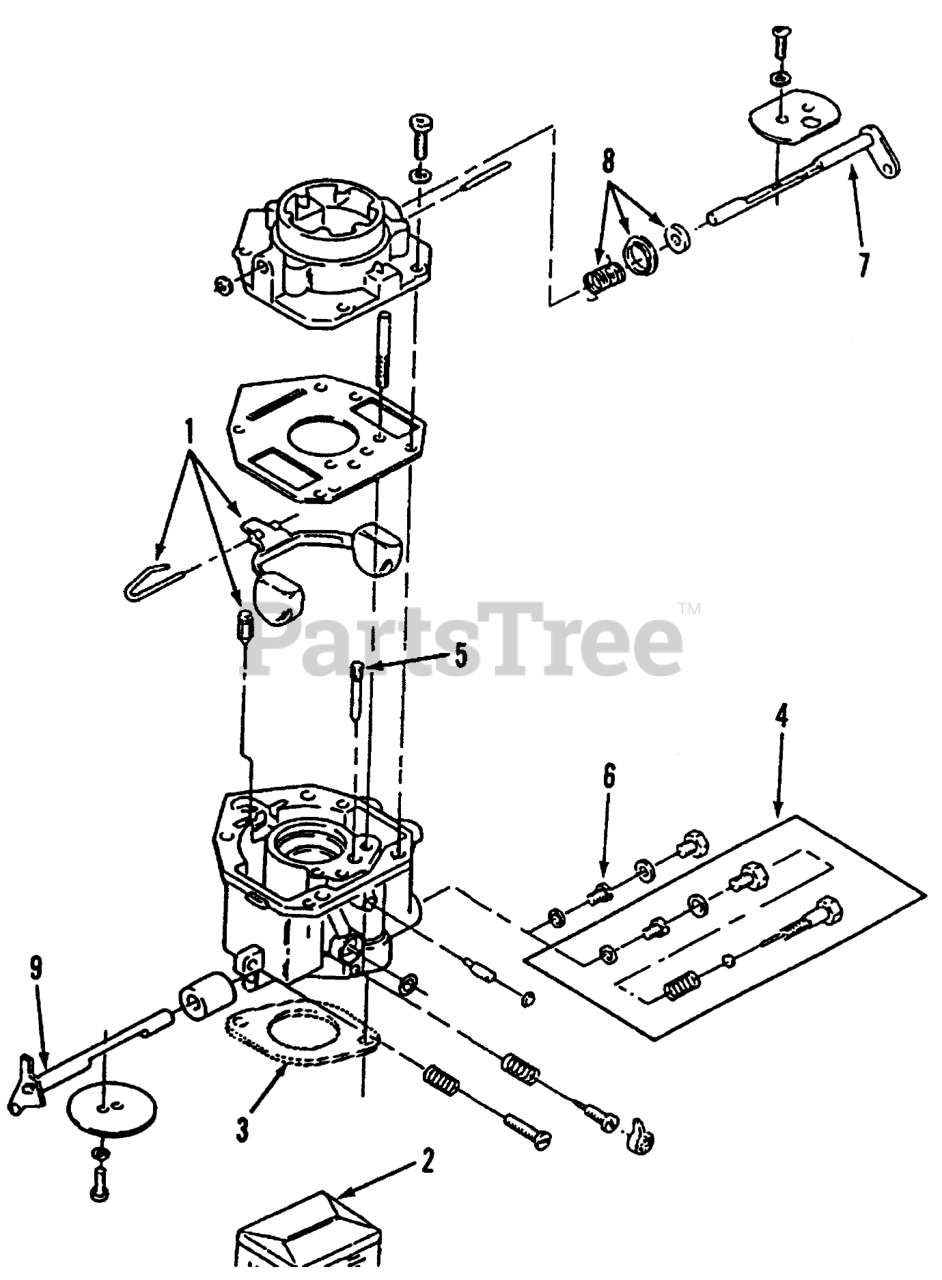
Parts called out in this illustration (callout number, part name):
1	Kit-Float (Includes Float, Pin, & Valve)
2	Kit-Repair (Includes Screw & Plug Package, Gasket Package, Float Valve, Idle Adjust Needle & Spring, Mounting Gaskets, & Idle Limit Cap)
3	Oil Fill Tube
4	FIXED-JET
5	Jet-Idle
6	POWER JET
7	Kit-Shaft, Choke (Includes Choke Valve, Valve Setscrew, & Air Filter)
8	Kit-Lever, Choke (Includes Choke Lever Ring, Choke Spring, & Choke Collar)
9	Kit-Shaft, Throttle (Includes Valve Setscrew, Air Filter, & Throttle Valve)
